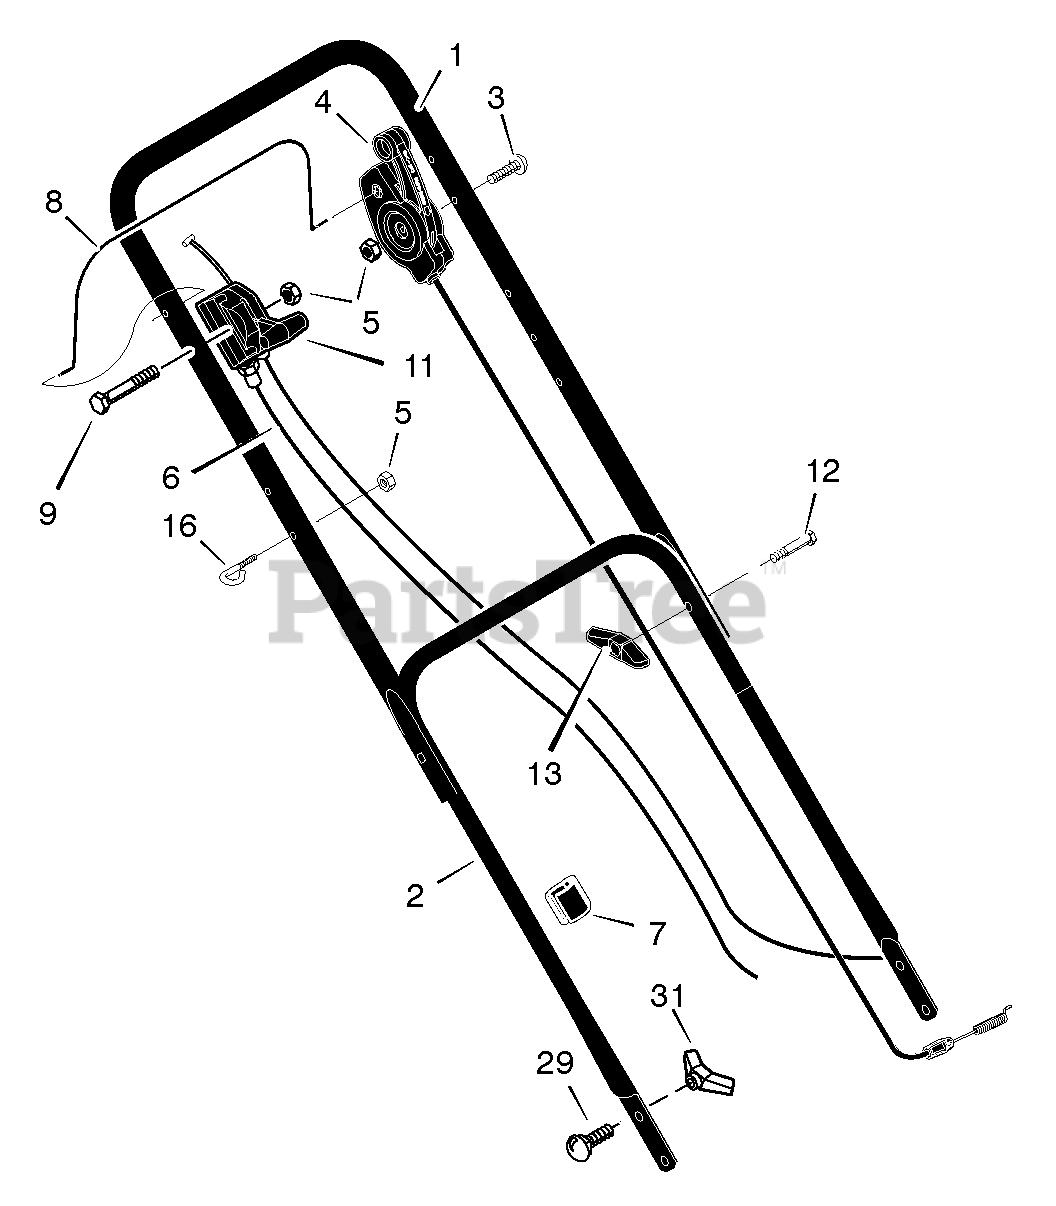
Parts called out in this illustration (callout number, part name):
1	Handle, Upper (Black)
2	Handle, Lower (Black)
4	Control, Drive
5	Locknut
6	Cable, Stop
7	Fastener, Cable
8	Lever, Stop
11	Control, Throttle
13	Knob
16	Guide, Rope
29	Bolt, Carriage
31	Knob, Plastic
